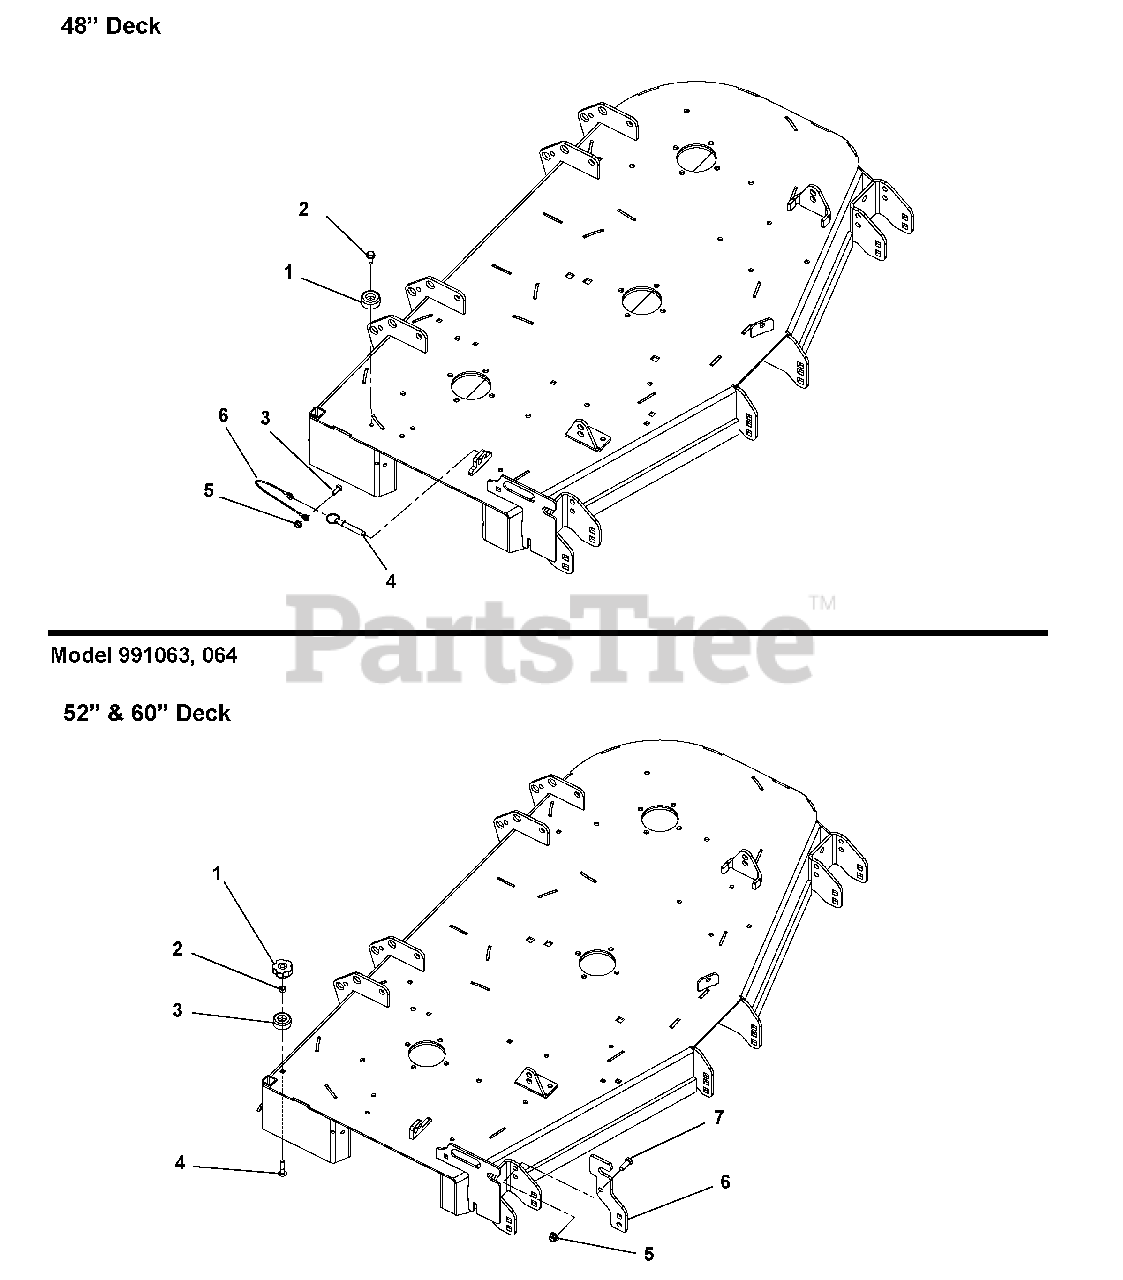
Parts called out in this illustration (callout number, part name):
1	Bumper, Recessed 1.50 x .63 w/.31 Thru Hole
2	Screw, Tapping .31-18 x .75 Hex Washer Head Thread Rolling
3	Bolt, Hex .25-20 x .75 Grade 5
4	Pin, Spring Ball .375OD x 1.50
5	Nut, Locking-Top-Flange .25-20
6	Cable, 6.0 Lanyard, Nylon
